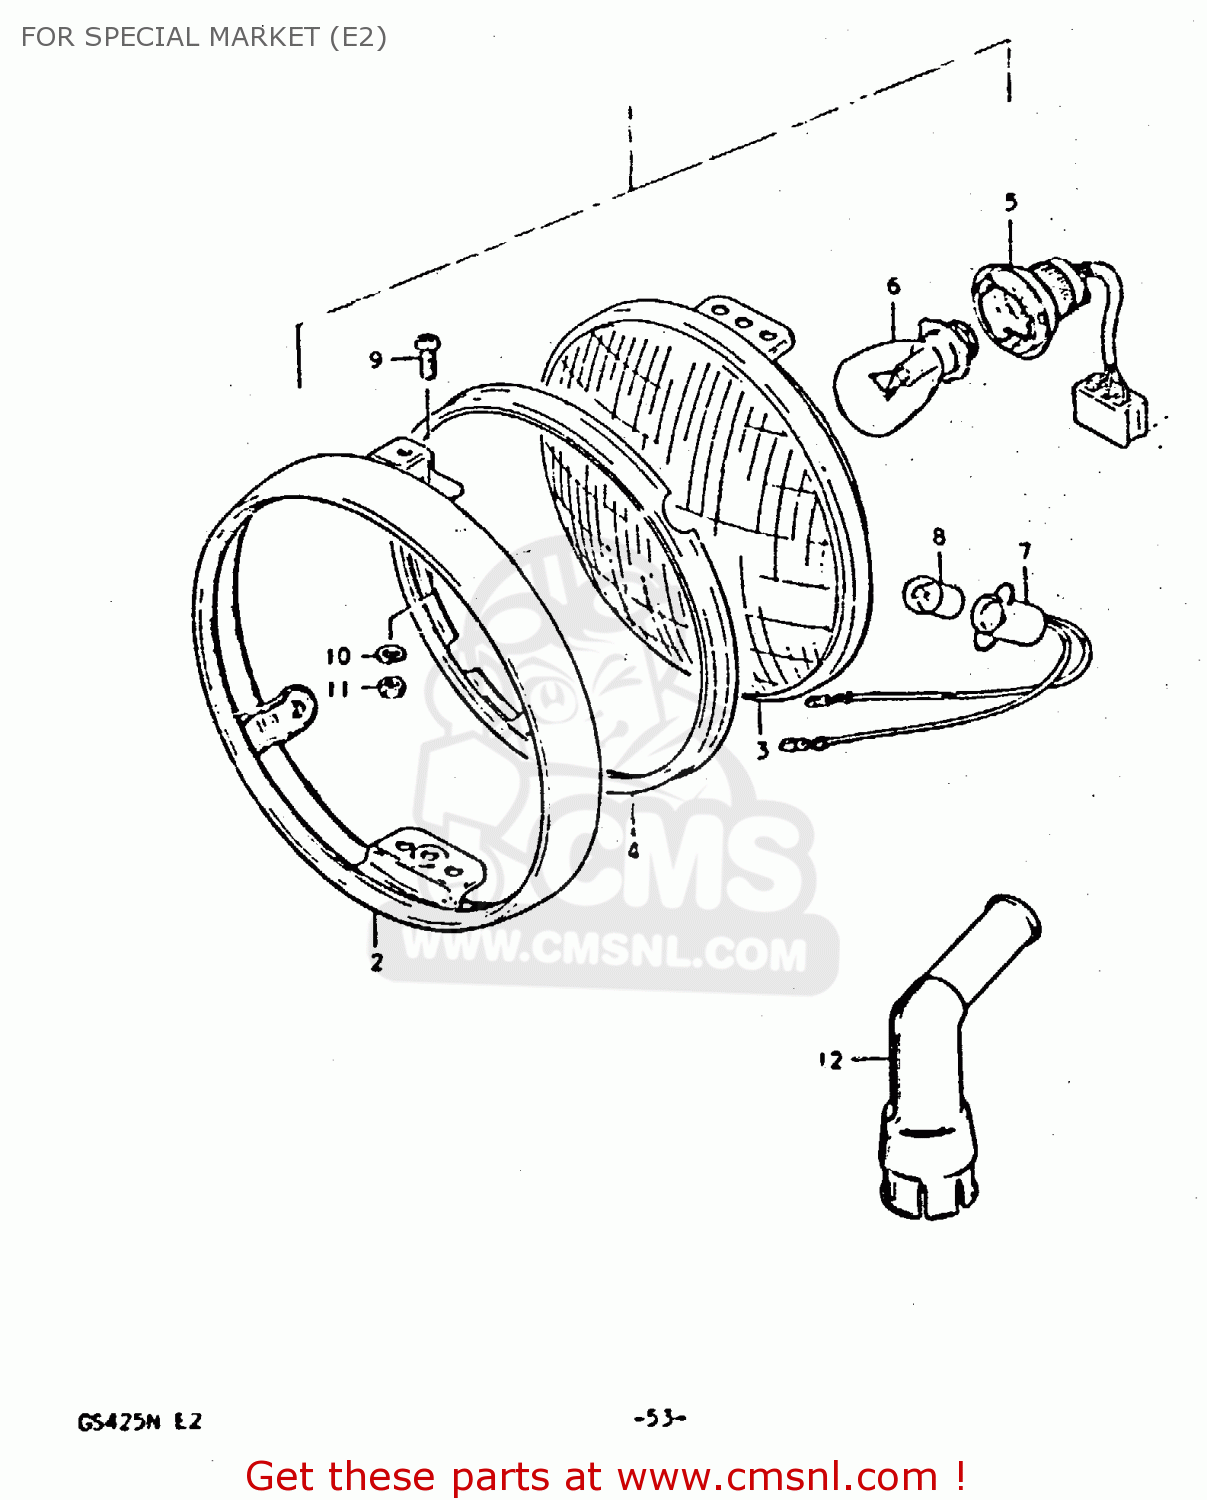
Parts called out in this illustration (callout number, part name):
1	HEADLAMP ASSY
2	RIM
3	UNIT, HEAD LIGHT
4	RETAINER,HEADLAMP
5	SOCKET
6	BULB 12V35/35W
7	SOCKET
8	BULB(12V3.4W,STANLEY,A72A)
9	SCREW
10	LOCK WASHER
11	NUT
12	CAP, SPARK PLUG (S)
